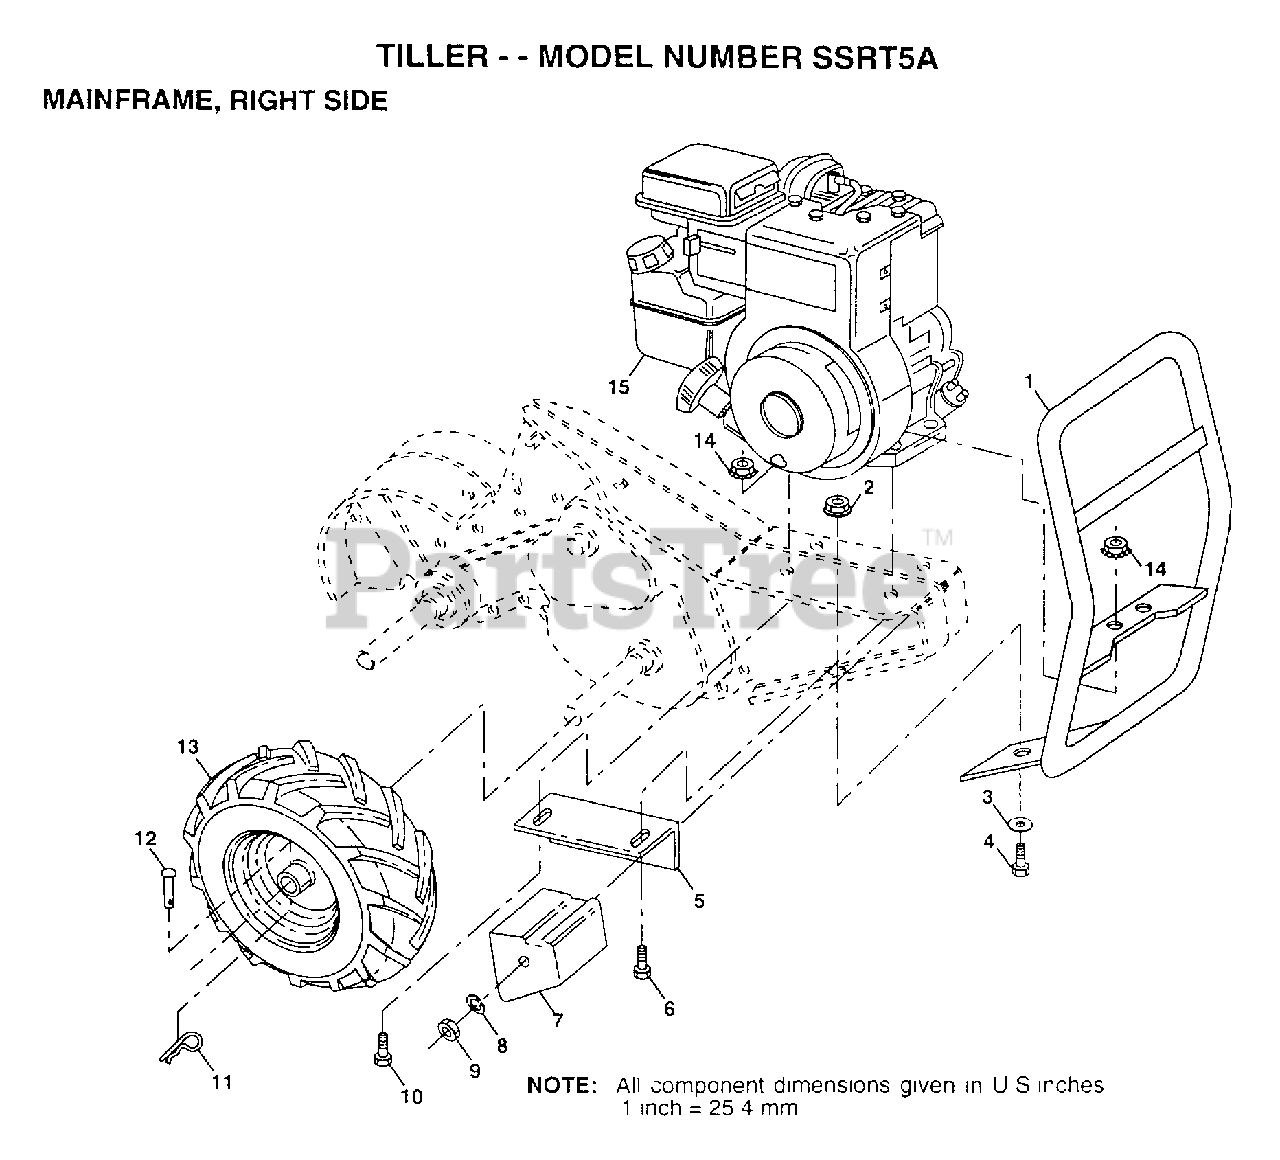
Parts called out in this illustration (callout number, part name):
1	BUMPER.ASM.TILL
2	LOCKNUT TI
3	WASHER
4	BOLT
5	BRKT REINFORCEMENT
6	BOLT
7	COUNTERWEIGHT CRT
8	LOCKWASHER
9	NUT.HEX.3/8-16UNC
10	BOLT.HEX.5/16-1.5
11	RETAINER M
12	RIVET DRILLED
13	TIRE TI
